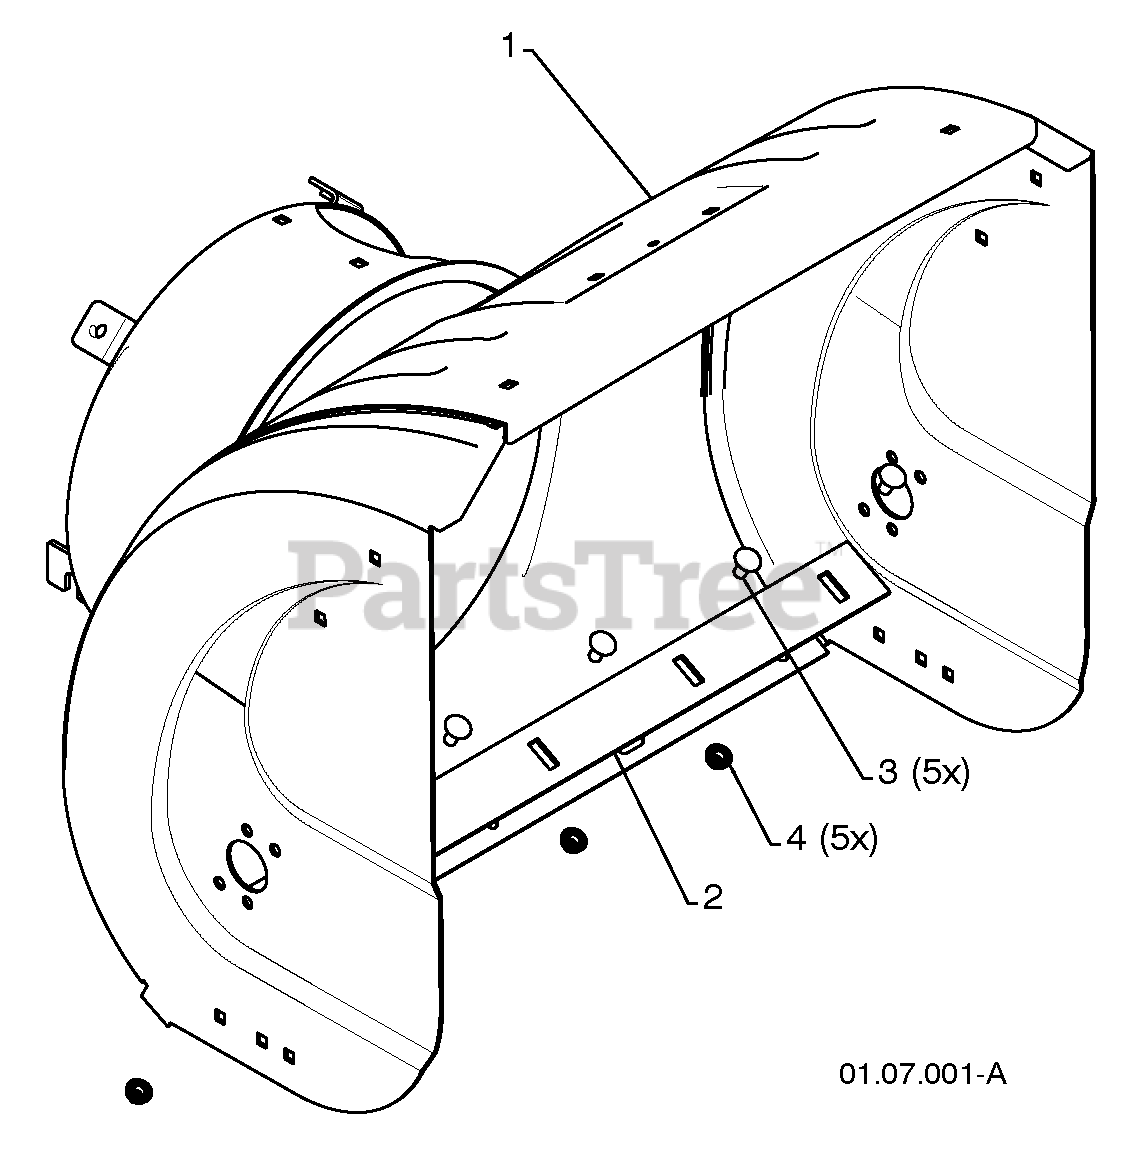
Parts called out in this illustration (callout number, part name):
1	AUGER HOUSING
2	SCRAPPER BAR
3	CARRIAGE BOLT 5/16-18 X .625
4	NUT 5/16-18
